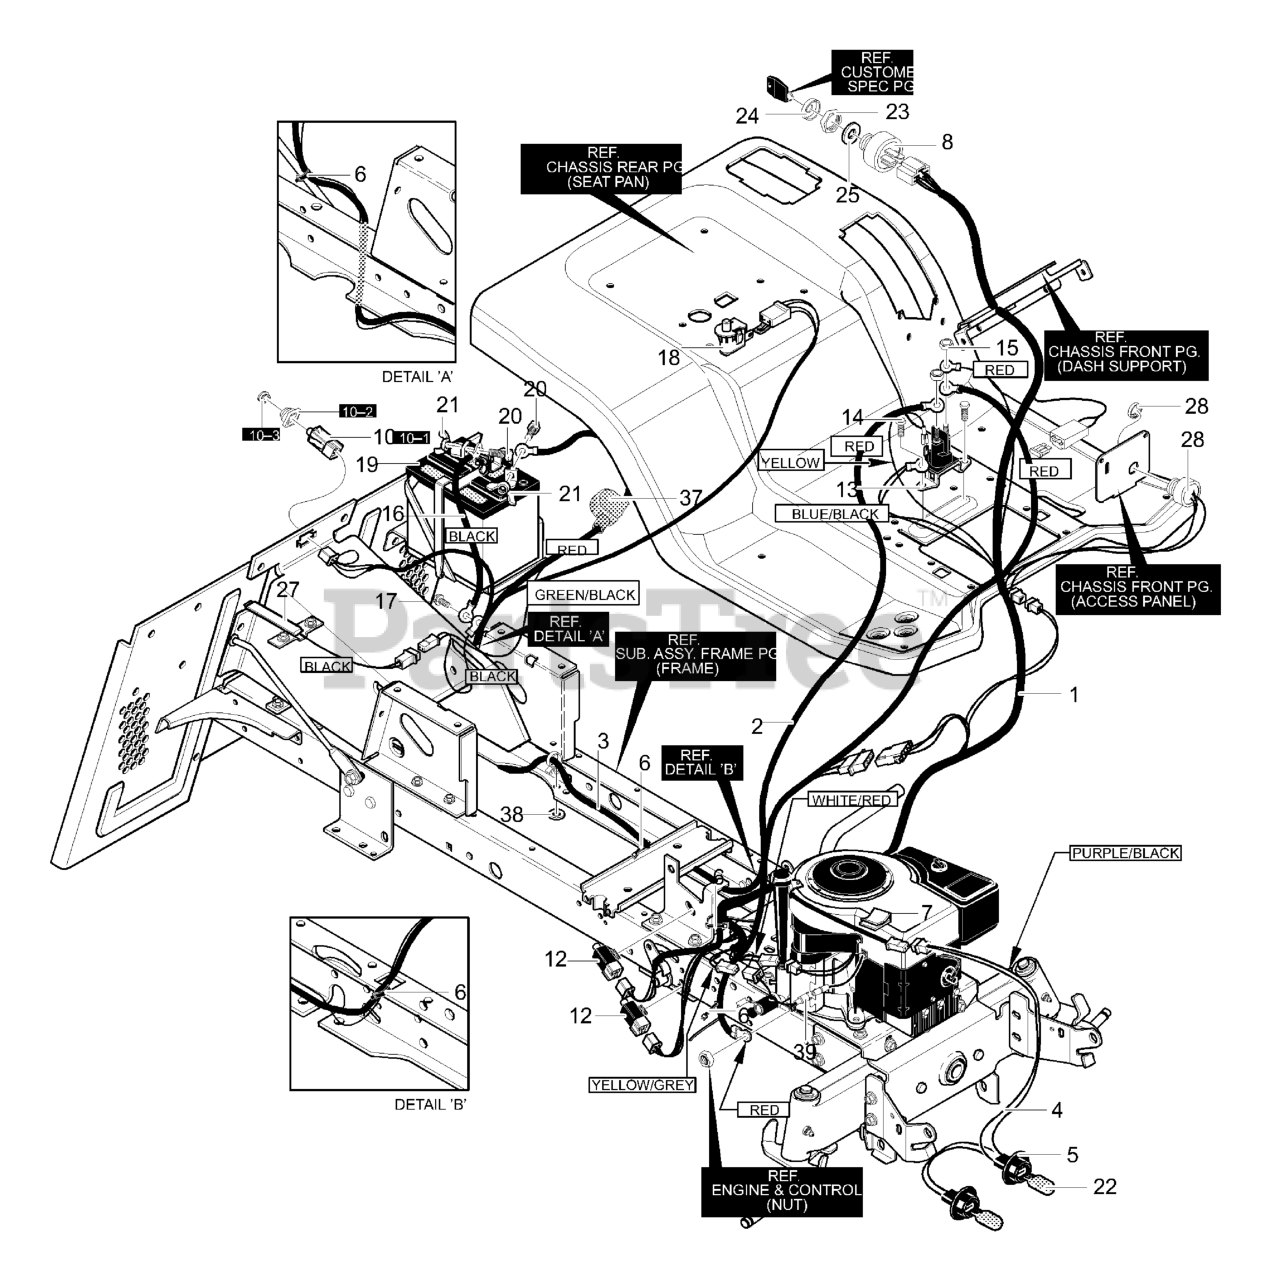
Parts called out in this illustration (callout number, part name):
1	Wire Harness
2	Wire, Lead Solenoid to Start
3	Rear Harness
4	Wire Harness, Headlight
5	Socket, Lamp
6	Cable Tie
7	Wire Clip, Adhesive
8	Switch, Ignition
10	Assy, Switch Double Pole Delta
10-1	Switch, Double
10-2	Boot, Switch
10-3	Switch Cap
12	Switch, Limit
13	Solenoid
14	Screw 1/4x.50
15	Nut, 1/4-20
16	Ground Wire
17	Screw, 1/4x.50
18	Seat Switch
19	Battery 5 Plate
20	Bolt, 1/4-20x.63
21	Wing Nut
22	Light Bulb
23	Nut, 5/8-8 Acme Delta
24	Boot, Ign. Switch
25	Washer, Regintlk
27	Tape Switch
28	Buzzer, For Bag Full
37	Boot, Battery
38	Flatwasher
39	Harness Adapter
